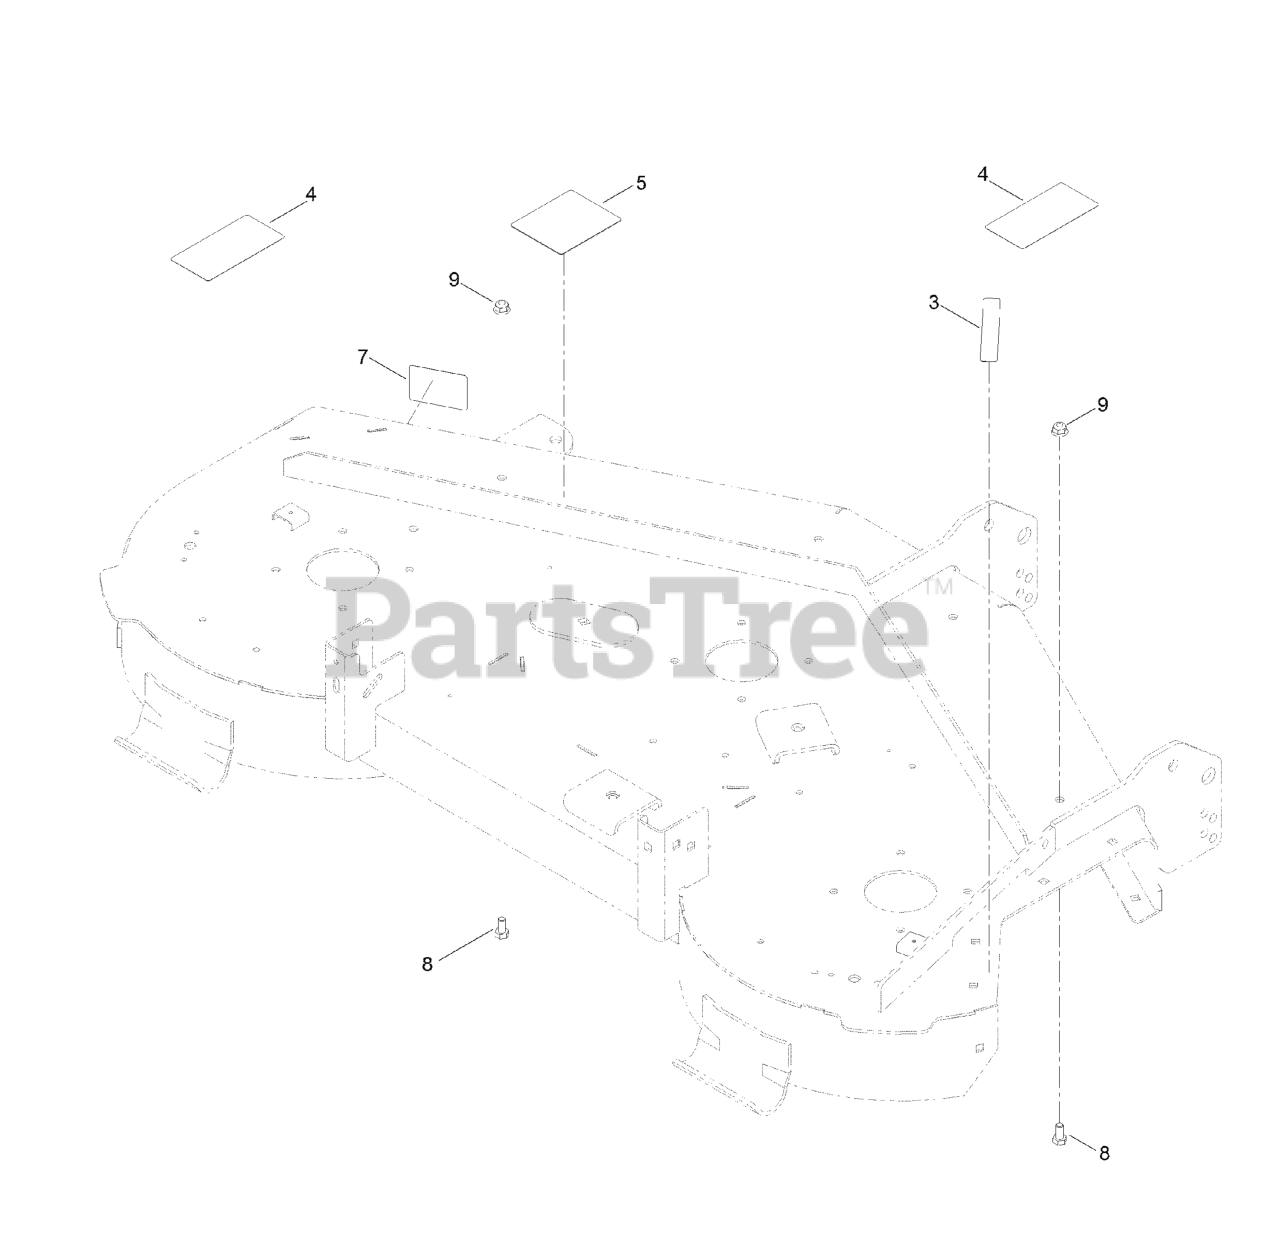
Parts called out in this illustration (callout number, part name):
3	DECAL-DANGER
4	DECAL-DANGER, DECK
5	DECAL-ROUTING, BELT
7	DECAL-SCALP, ANTI
8	SCREW-HH
9	NUT-HF, NI
